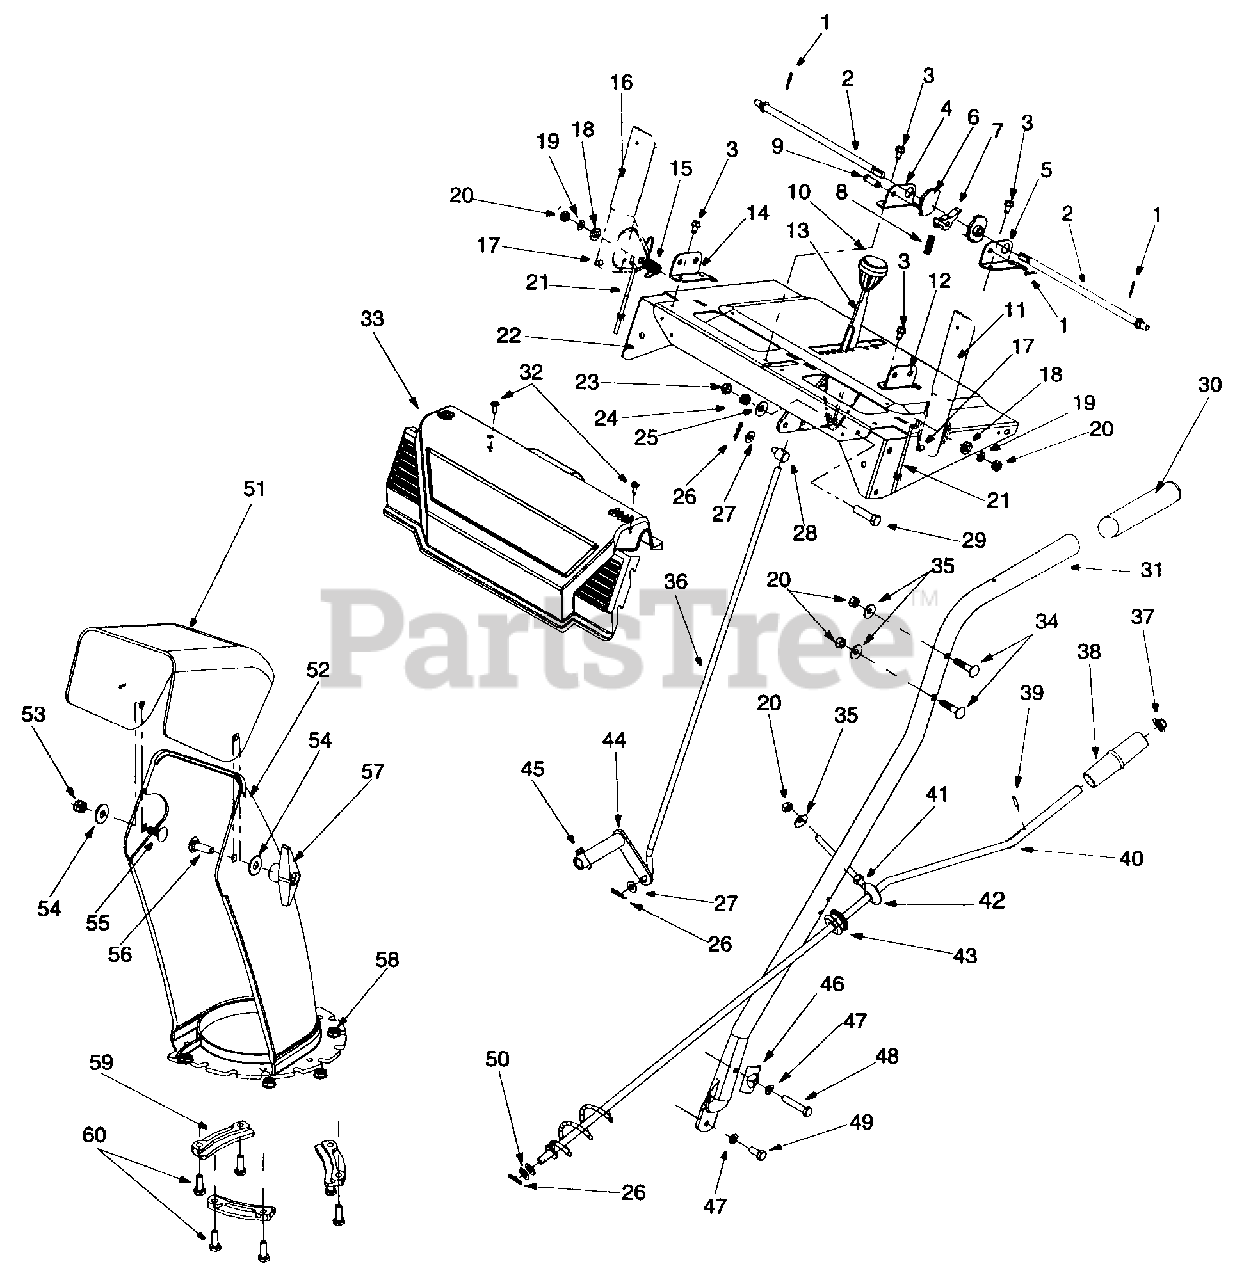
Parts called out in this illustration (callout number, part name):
1	Cotter Pin
3	Hex Washer Screw 1/4-20 x .5
7	Handle Lock Pawl
8	Compression Spring
9	Clevis Pin
10	Knob
11	Handle Assy - LH
15	Torsion Spring
16	Handle Assy - RH
17	Rubber Bumper
19	Lock Washer 5/16
20	Hex Nut 5/16-18
21	Cable
24	Compression Spring
25	Bell Washer
26	Cotter Pin
27	Flat Washer 5/16
28	Ferrule
29	Hex Cap Screw 3/8-24 x 1.50
33	Handle Panel
34	Carriage Bolt 5/16-18 x 1.50
35	Bell Washer .340 ID x .872 OD
38	Chute Knob
39	Roll Pin
40	Chute Crank
41	Hex Nut 5/16-18
42	Chute Crank Eyebolt
43	Rubber Grommet
46	Handle Tab
47	Lock Washer 5/16
48	Hex Cap Screw 5/16-18 x 1.75
49	Hex Cap Screw 5/16-18 x .75
50	Flat Washer
51	Upper Chute
52	Lower Chute
53	Hex Lock Nut 5/16-18
54	5/16 Washer
55	Carriage Bolt 5/16-18 x .75
56	Carriage Screw 5/16-18 x 1.0
58	Hex Lock Nut 1/4-20
59	Flange Keeper
60	Hex Cap Screw 1/4-20 x .75
